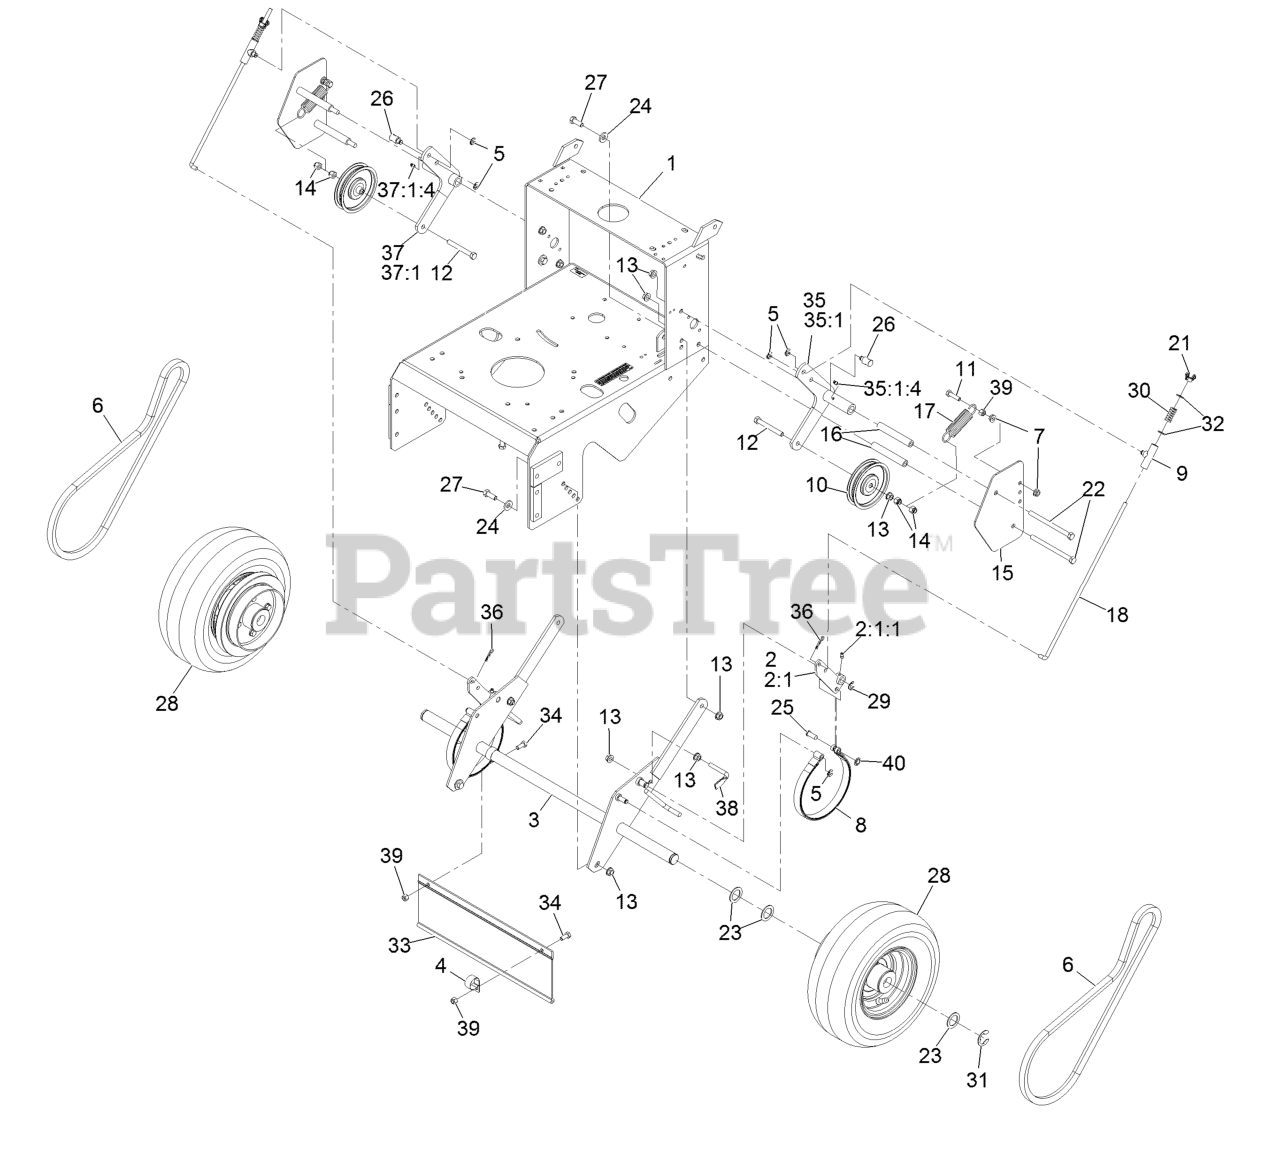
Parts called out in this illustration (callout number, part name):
1	ASM, Metro Engine Deck W/Decals
2	Arm-Brake
2:1	Wld,Brake Arm
2:1:1	Asm,Bushing/Zerk
4	Clamp-R
5	Ring-Retaining
6	Belt-Wheel, Drive
7	Nut-Whizlock 5/16-18
8	Band-Brake
9	Swivel-Brake
10	Idler-Wheel, Drive
11	Screw,HH Special 5/16-18 X 1.25
12	Bolt-HH 3/8-16 X 3 Tap
13	Nut-Whizlock 3/8-16
14	Nut-Nyloc 3/8-16
15	Shield-Wheel, Drive
16	Spacer-Shield
17	Spring-Extension
18	Linkage-Brake
21	Wingnut-Nyloc 5/16
22	Screw-HH 3/8-16 X 5
23	Washer-Spacer
24	Washer-Spring Disc 3/8
25	Pin-Clevis 1/2 X 1
26	Swivel-Lever, Drive
27	Screw-HH 3/8-16 X 1
28	Drive Wheel ASM
29	Ring-Retaining
30	Spring-Compression
31	Ring-Snap
32	Washer-5/16 SAE
33	Shield-Trailing
34	Screw-HH 5/16-18 X 3/4
35	Arm-Idler, LH
35:1	Idler Arm LH Assy
35:1:4	Fitting-Grease
36	Hairpin-Cotter
37	Arm-Idler, RH
37:1	Idler Arm RH Assy
37:1:4	Fitting-Grease
38	Scraper
39	Nut-Nyloc 5/16-18
40	Nut-Push 3/8
